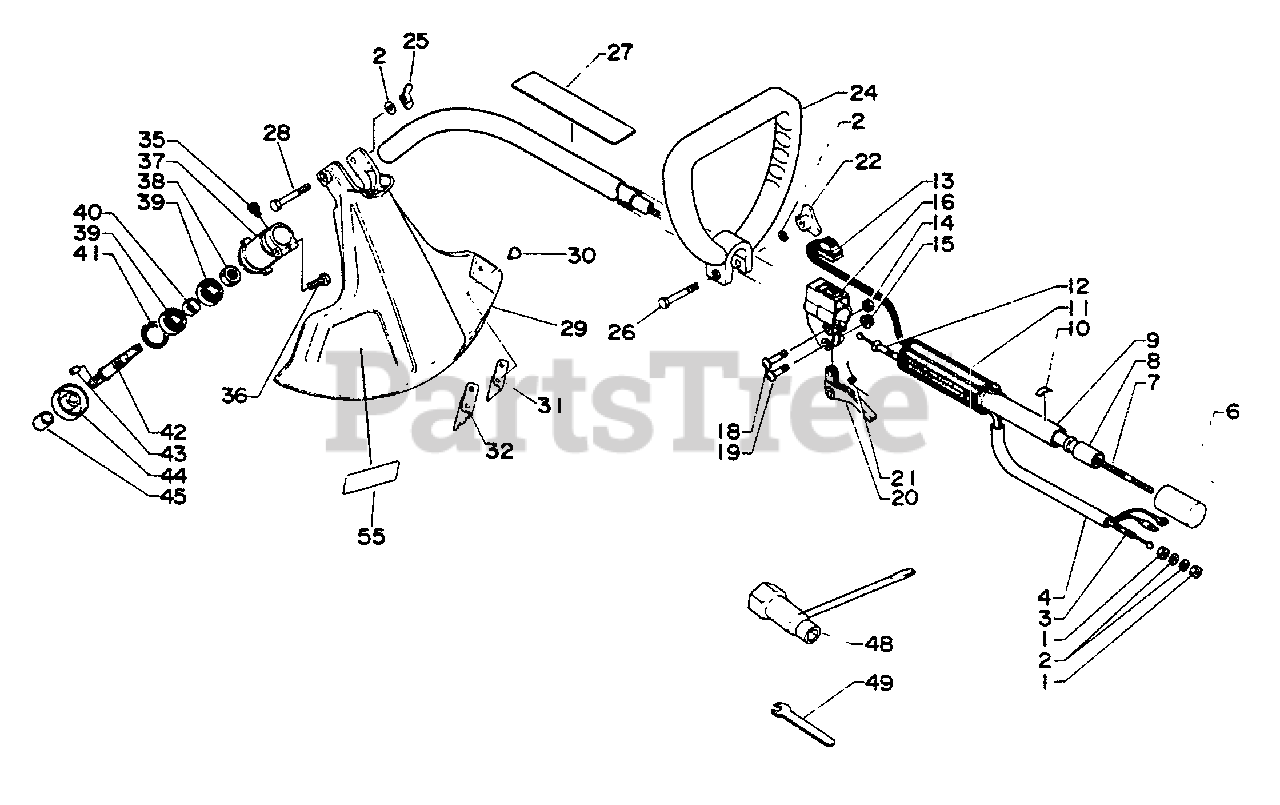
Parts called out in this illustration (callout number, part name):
2	WASHER - 6
3	CABLE, THROTTLE
4	TUBE - VINYL
6	Cap, housing
7	DRIVESHAFT - FLEXIBLE
8	BUSHING
9	PIPE, MAIN
10	LABEL - ALIGNMENT
11	GRIP, HANDLE
12	GUIDE, CABLE
13	IGNITION SWITCH ASSY
15	LOCKNUT - 5
16	BRACKET, THROTTLE
18	SCREW - 5X28
19	SCREW - 5X30
20	TRIGGER, THROTTLE
21	SPRING, TRIGGER
22	KNOB, FASTENER
24	HANDLE
25	WINGNUT - 6
26	BOLT - 6X40
27	LABEL - CAUTION
28	BOLT - 6X50
29	SHIELD, DEBRIS - PLASTIC
30	SCREW - 5X16
31	KNIFE, TRIMMER LINE
32	GUARD
35	SCREW - 4X10
36	BOLT - 5X25
37	CASE, GEAR
38	NUT - 12 -- LEFT HAND
39	BEARING, BALL - 6001 DDU
41	RING, RETAINING - 28
42	GEAR - SHAFT
43	PIN - 3X6
44	ADAPTOR, BLADE - UPPER
45	CAP, DRIVESHAFT
48	T-WRENCH - 8X19mm
49	SPANNER - 10mm
55	LABEL - ECHO
